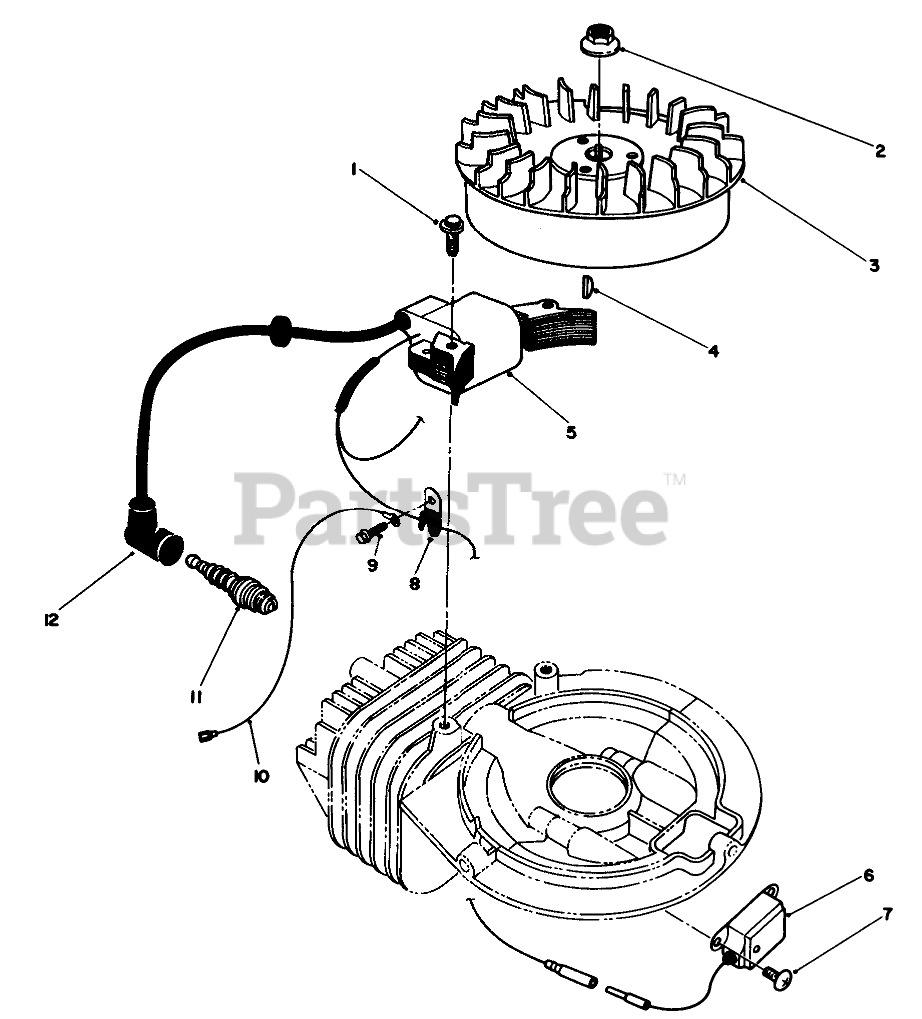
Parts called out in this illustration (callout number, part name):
1	SCREW
3	FLYWHEEL
5	MAGNETO COIL
6	MAGNETO MODULE
7	SCREW
8	CLAMP
11	Sparkplug
12	CAP-SPARKPLUG
